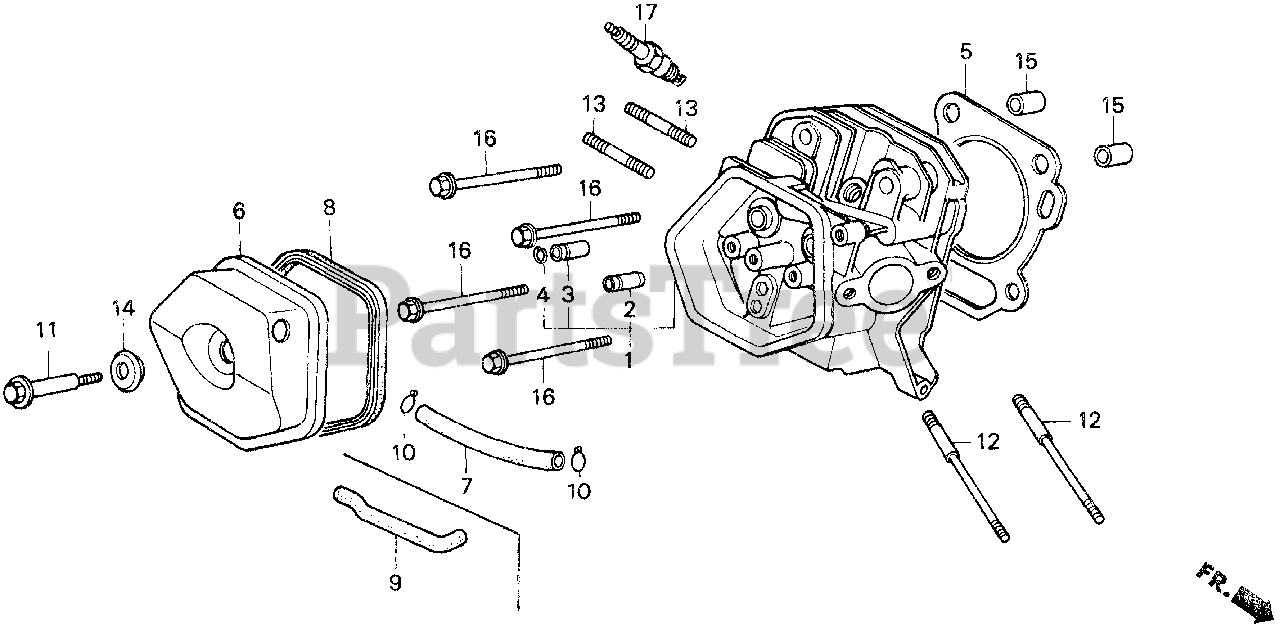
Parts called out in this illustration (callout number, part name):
1	CYLINDER HEAD
2	GUIDE, VALVE (OS)
3	GUIDE, EX. VALVE (OS)
4	CLIP, VALVE GUIDE
5	GASKET, CYLINDER HEAD
6	COVER, HEAD
7	TUBE, BREATHER
8	GASKET, CYLINDER HEAD COVER
10	CLIP, BREATHER TUBE
11	BOLT, HEAD COVER
12	BOLT, STUD (8X131.5)
13	BOLT, STUD (8X47)
14	WASHER, HEAD COVER
15	PIN A, DOWEL (12X20)
16	BOLT, FLANGE (10X80)
17	SPARK PLUG (BPR5ES) (NGK)
17	SPARK PLUG (W16EPR-U) (DENSO)
17	SPARK PLUG (BPR6ES) (NGK)
17	SPARK PLUG (W20EPR-U) (DENSO)
